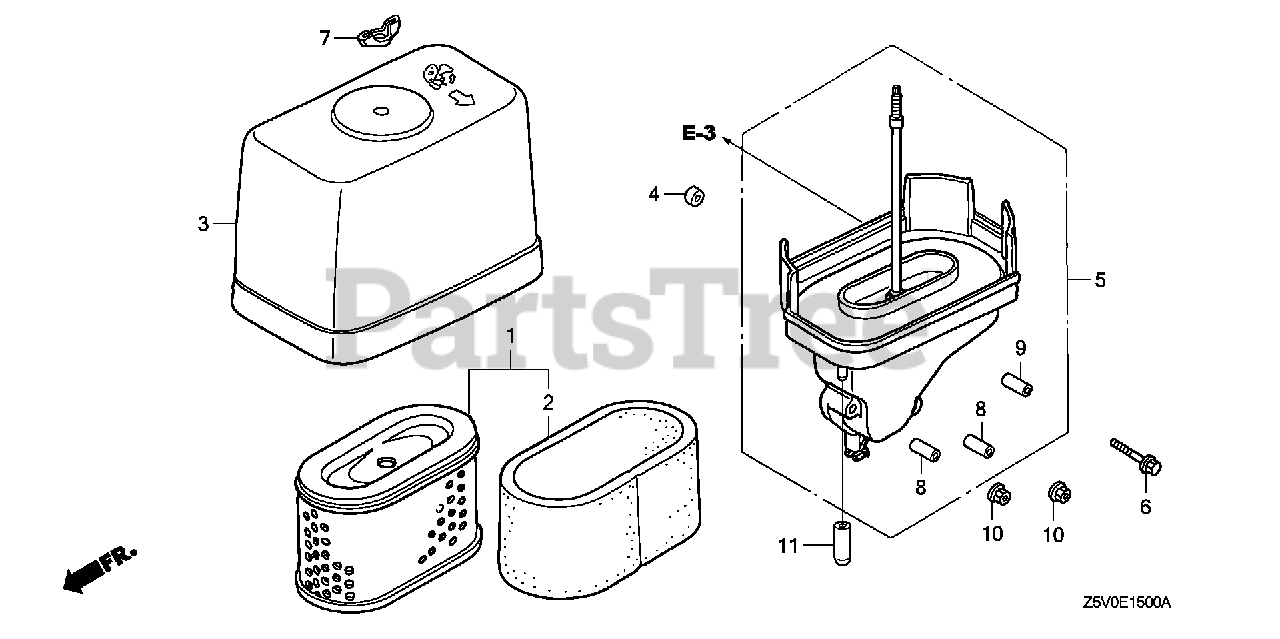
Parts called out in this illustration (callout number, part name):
1	ELEMENT, AIR CLEANER
1	ELEMENT, AIR CLEANER (PLASTIC BASE)
2	FILTER (OUTER)
3	COVER, AIR CLEANER
5	ELBOW, AIR CLEANER
6	BOLT, FLANGE (6X35) (CT200)
7	NUT, TOOL BOX SETTING
8	COLLAR, AIR CLEANER
9	COLLAR, AIR CLEANER
10	NUT, FLANGE (6MM)
11	CAP, SEALING
